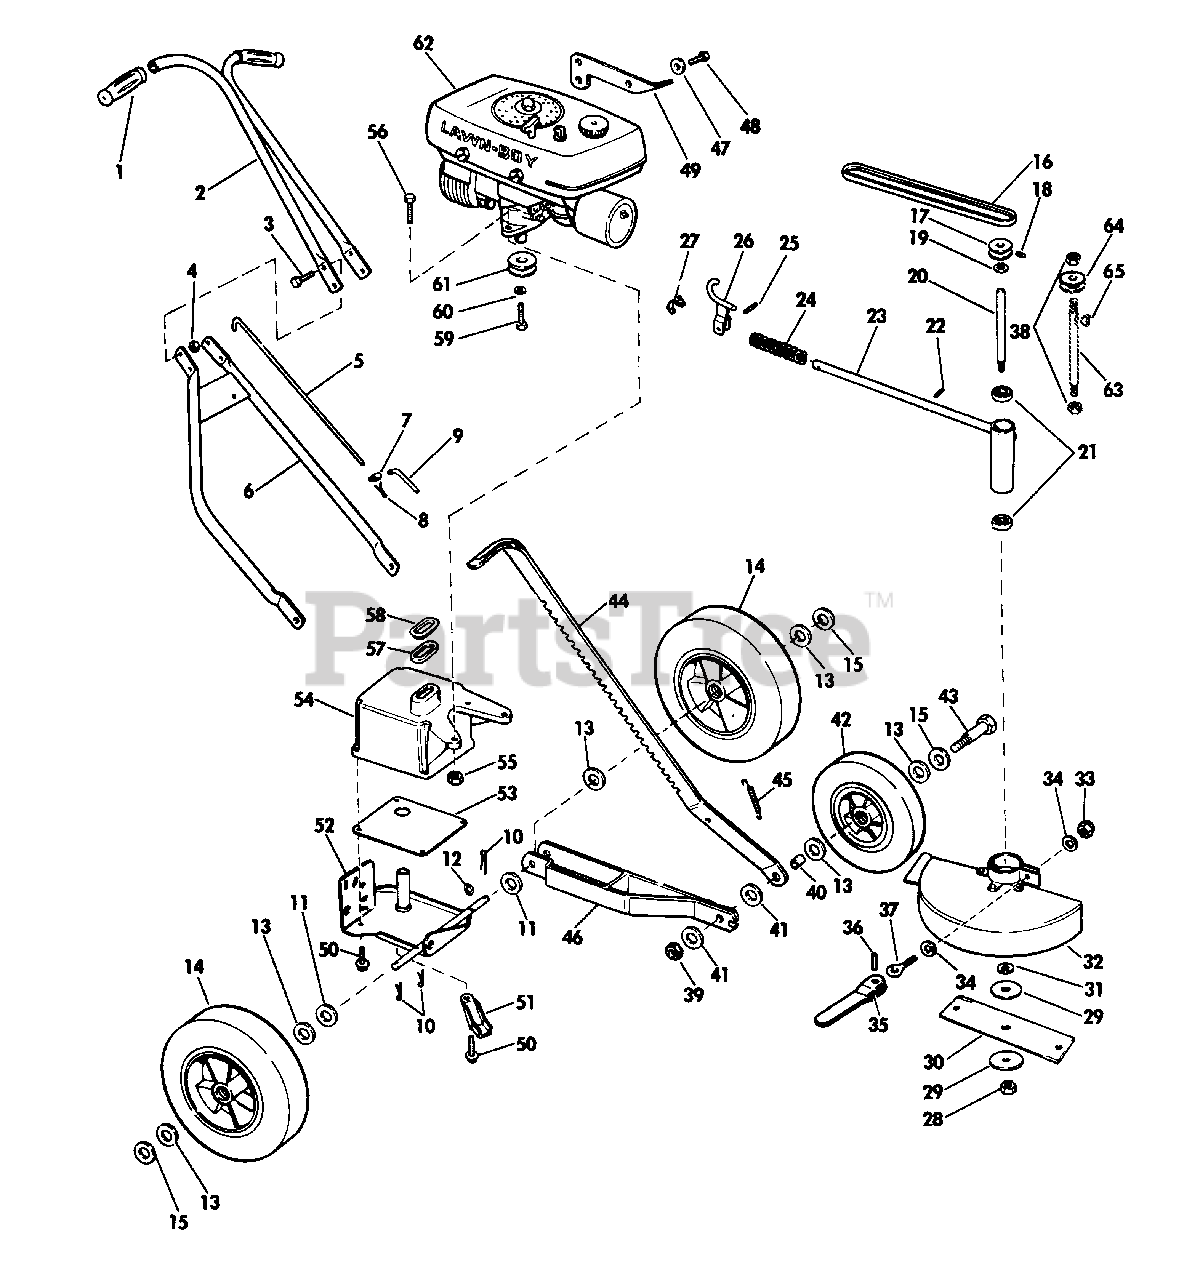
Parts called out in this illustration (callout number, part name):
1	Grip-Handle, Blue
2	Handle Assembly, Top
3	Screw-Handle Truss Head
4	Nut-Nylok Stop
5	Rod-Handle Adjusting
6	Handle Assembly, Bottom
7	Clamp-Rod
8	Pin-Cotter
9	Lever-Rod Clamp
10	Pin-Cotter
11	Washer
12	Grip Ring
13	Washer, Felt
14	Wheel and Tire Assembly 8"
15	Washer
16	Belt-4L-240
17	Pulley-Driven
18	Screw-Socket Set
19	Grip Ring
20	Shaft-Spindle
21	Bearing-Seal Ball 9/16"
22	Pin-Groove
23	Spindle Housing and Pivot Assy.
24	Spring-Comp.
25	Pin-Spring
26	Locking Pin and Lever Assy.
27	Spring-Locking Lever
28	Nut-Stop
29	Washer
30	Blade-9"
31	Washer, Blade
32	Guard and Clamp Assembly
33	Nut Lock
34	Washer-Plain
35	Lever Assembly
36	Roll Pin
37	Eye Bolt
38	Nut
39	Nut, Wheel, Shoulder Bolt
40	Sleeve, Wheel Bracket
41	Washer, Wheel
42	Wheel and Tire Assembly 6"
43	Bolt, Wheel
44	Lever, Wheel Adjusting
45	Spring, Wheel Height Adj.
46	Wheel Bracket and Spacer Assembly
47	Washer, Bracket to Shroud
48	Screw
49	Bracket, Wheel Height Adj.
50	Screw-Thread Cutting
51	Deflector, Muffler
52	Axle and Muffler Plate Assembly
53	Gasket-Muffler
54	Muffler-Edger
55	Nut-Nylok
56	Screw-Hex Hd. Machine
57	Gasket-Exhaust
58	Sleeve-Exhaust Gasket
59	Screw
60	Lockwasher
61	Pulley-Drive
62	Engine, Model D-462
63	Shaft-Spindle
64	Pulley-Driven
65	Key-Shaft
